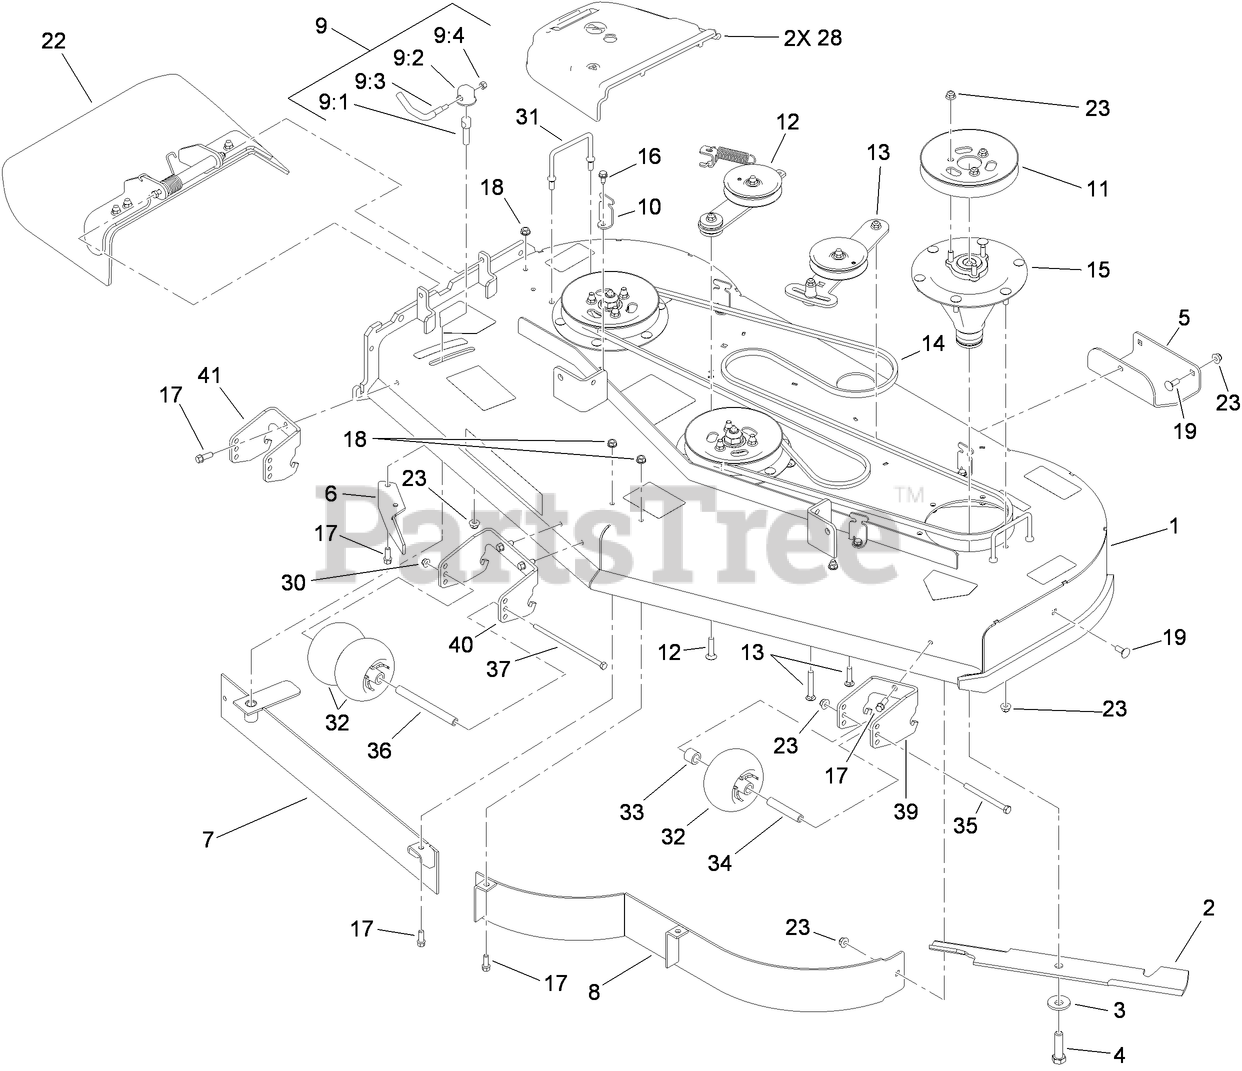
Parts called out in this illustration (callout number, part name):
1	DECK ASM
2	BLADE-HI FLOW
3	Washer-Blade Bolt, Heavy
4	SCREW-BLADE
6	BAFFLE-DISCHARGE
7	BAFFLE ASM
8	BAFFLE ASM
9	LEVER ASM
9:1	Screw-Lock
9:2	CAP-LOCK
9:3	Lever-Lock
9:4	NUT-LOCK, NI
10	BRACKET-COVER
11	Pulley
12	SPRING IDLER ASM
13	IDLER ADJUST ASM
14	BELT-V
15	SPINDLE ASM
16	SCREW-HWHTF
17	SCREW-HWH
18	NUT-HHF, WHIZ
19	BOLT-CARR
22	DEFLECTOR ASM
23	NUT-HF, NI
28	COVER-BELT, LH
30	NUT-HF, NI
31	WIREFORM-COVER
32	ROLLER-SCALP, ANTI
33	TUBE-SPACER
34	TUBE-SPANNER
35	SCREW-HH
36	SPACER-WHEEL
37	SCREW-HH
39	BRACKET-WHEEL, LH
40	BRACKET-WHEEL, CENTER
41	BRACKET-WHEEL, RH
